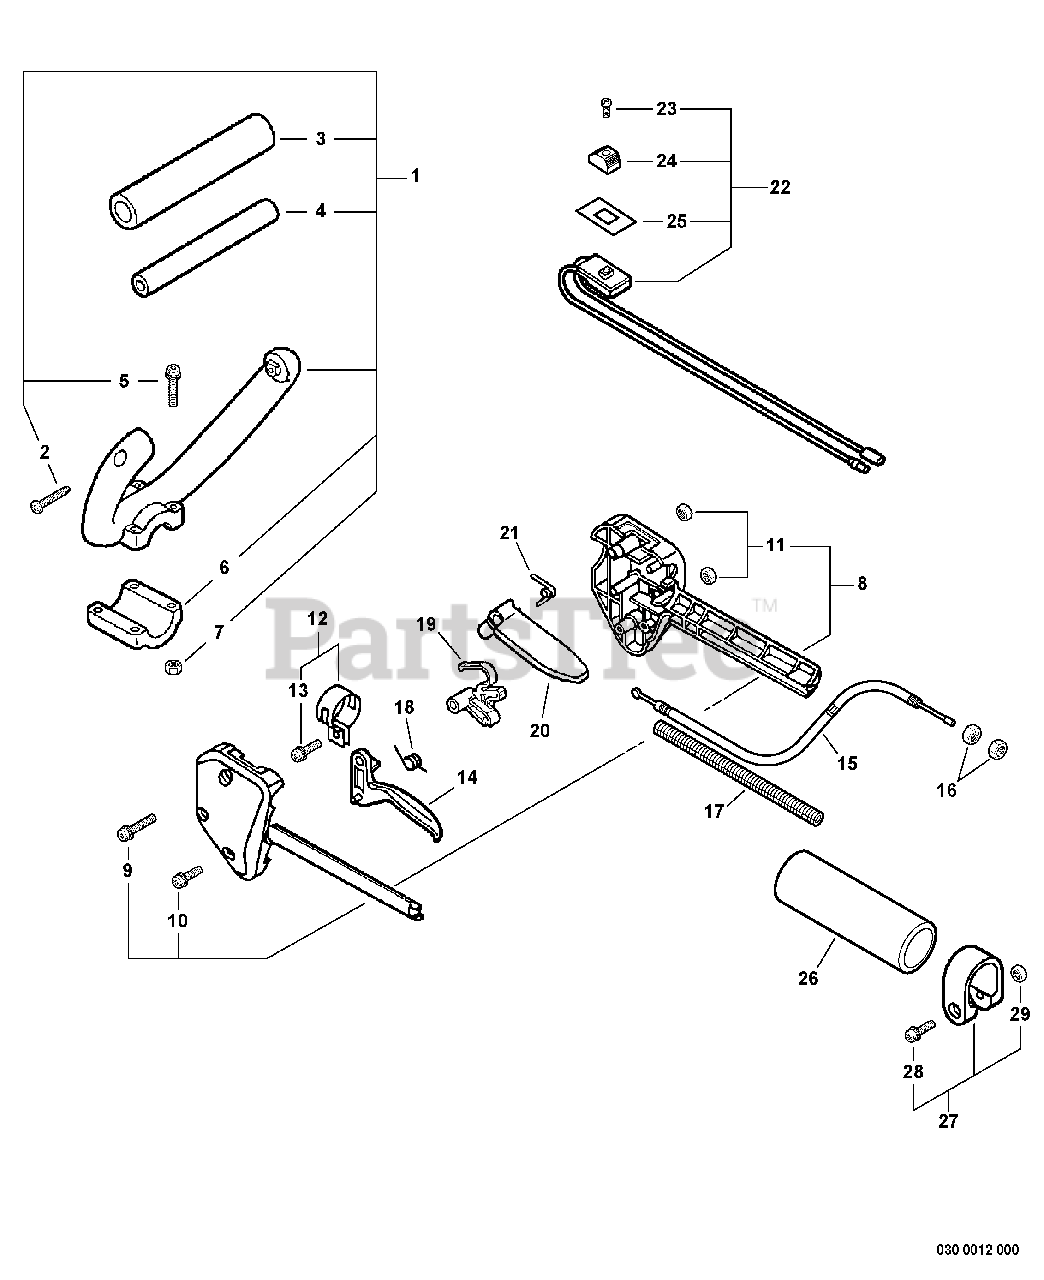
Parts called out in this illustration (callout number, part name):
1	LOOP HANDLE ASSY
2	SCREW - 5X30
3	GRIP, HANDLE
5	SCREW - 5X35
6	BRACKET, HANDLE - LOWER
8	CONTROL HANDLE KIT
9	SCREW - 5X35
10	SCREW - 5X25
12	CLAMP KIT
13	SCREW - 5X14
14	TRIGGER, THROTTLE
15	CABLE, THROTTLE
17	TUBE, PROTECTIVE - CORRUGATED
18	SPRING, TRIGGER
19	LOCKOUT, THROTTLE
20	LEVER, TRIGGER LOCKOUT
21	SPRING, LOCKOUT LEVER
22	IGNITION SWITCH ASSY
23	SCREW - 3X10
24	KNOB, SWITCH - ORANGE
25	COVER, SWITCH - STOP
26	GRIP, HANDLE
27	CLAMP KIT
28	SCREW - 5X28
